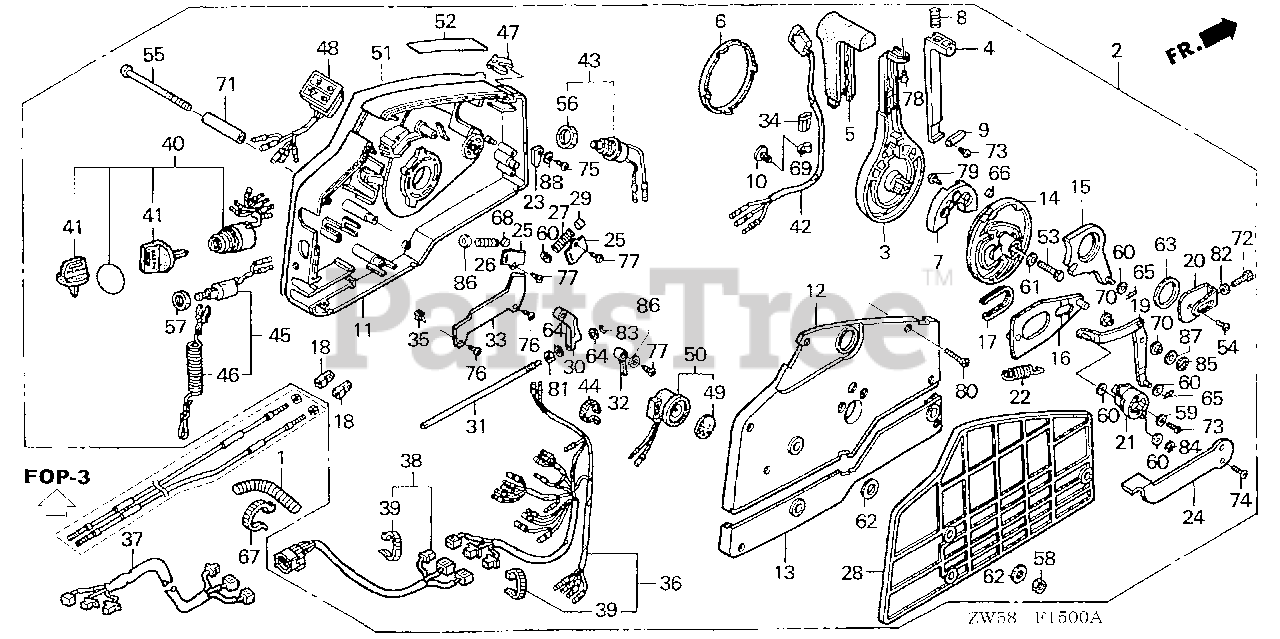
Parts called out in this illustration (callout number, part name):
1	TUBE, CORRUGATE (28MM)
2	S/R SW 2 LIGH POW TL
2	BOX ASSY., REMOTE CONTROL (P/T)
2	BOX ASSY., REMOTE CONTROL (P/T)(HI-LEX)
3	HANDLE, REMOTE CONTROL
4	LEVER, HANDLE LOCK
5	GRIP, REMOTE CONTROL HANDLE
6	CAP, HANDLE
7	BLOCK, NEUTRAL LOCK
8	SPRING, REMOTE CONTROL HANDLE
9	PLATE, LEVER SETTING
10	CLAMP, HARNESS
11	HOUSING, REMOTE CONTROL BOX (A)
12	HOUSING, REMOTE CONTROL BOX (B)
13	HOUSING, REMOTE CONTROL BOX (C)
14	WHEEL, CONTROL
15	ARM, SHIFT LINK
16	PLATE, SLIDING
17	COLLAR, SLIDING PLATE
18	PIVOT, SHIFT
19	ARM, LINK JOINT
20	BRACKET, LINK JOINT
21	WHEEL, ACCELERATOR
22	SPRING, ACCELERATOR WHEEL
23	CAM, STARTER SWITCH
24	LEVER, IDLE
25	PLATE, SPRING SETTING
26	SPRING, SHIFT CLICK
27	SPRING, CHOKE RETURN
28	SPACER, REMOTE CONTROL BOX
29	SPACER, CLICK SPRING
30	BLOCK, THROTTLE FRICTION
31	BOLT, FRICTION
32	SPACER, NEUTRAL SWITCH
33	CLAMP, POWER TILT CORD
34	PIPE, HARNESS GUIDE
35	SPACER, CABLE CLAMP
36	CABLE ASSY., REMOTE CONTROL (B)
37	CABLE ASSY., REMOTE CONTROL EXTENSION
38	CABLE ASSY., SWITCH PANEL
39	TIE, CABLE (2.4X92) (NATURAL)
40	SWITCH ASSY., COMBINATION
41	KEY ASSY., COMBINATION SWITCH (35100-ZV5-003 ONLY)
42	SWITCH ASSY., POWER TRIM-TILT
43	SWITCH ASSY., SOLENOID
44	BAND (BLACK 3.5X140)
45	SWITCH ASSY., EMERGENCY STOP
46	WIRE, EMERGENCY
47	CLIP, EMERGENCY LOCK
48	LAMP ASSY., INDICATION (2-LED)
49	PLATE, TURN SIGNAL BUZZER
50	BUZZER, WARNING
51	PLATE, REMOTE CONTROL (CAUTION PICT=SILVER)
52	MARK, FAST IDLE
53	BOLT, HEX. (8X35)
54	SCREW, PAN (6X10)
55	SCREW (6X95)
56	NUT, HEX. (20MM)
57	NUT, HEX. (16MM)
58	NUT, HEX. (6MM)
59	WASHER, PLAIN (5MM)
60	WASHER, PLAIN (6MM)
61	WASHER, PLAIN (8MM)
62	WASHER (6MM)
63	WASHER (28MM)
64	WASHER, PLAIN (4MM)
65	PIN, LOCK (6MM)
66	PIN (6X6)
67	BAND, SELF-LOCK
68	ROLLER, CLICK
69	CLIP, WIRE HARNESS (6.3MM)
70	COLLAR, LINK JOINT
71	COLLAR, DISTANCE (6X10X43.5)
72	BOLT, HEX. (5X16)
73	SCREW, PAN (5X10)
74	SCREW, OVAL (5X12)
75	SCREW, TAPPING (4X10)
76	SCREW, TAPPING (5X8)
77	SCREW, TAPPING (5X10)
78	SCREW, TAPPING (5X12)
79	SCREW, TAPPING (6X16)
80	SCREW, TAPPING (5X25)
81	NUT, HEX. (6MM)
82	NUT, HEX. (5MM)
83	E-RING (3MM)
84	E-RING (4MM)
85	E-RING (7MM)
86	WASHER, PLAIN (5MM)
87	WASHER, PLAIN (8MM)
88	WASHER, PLAIN (4MM)
